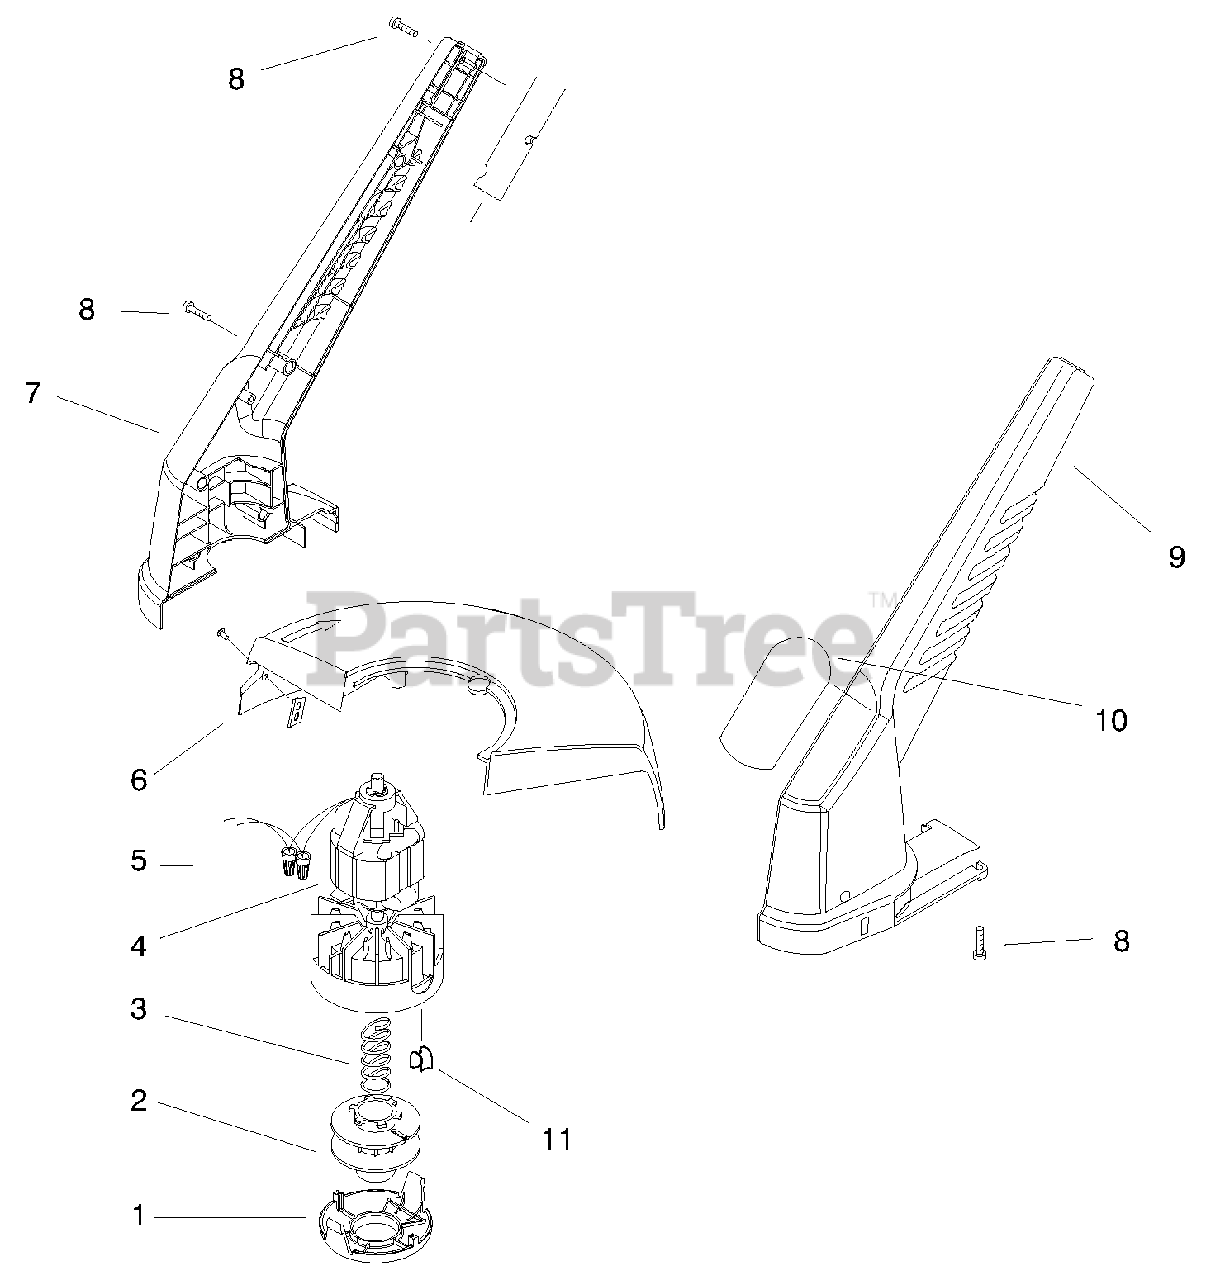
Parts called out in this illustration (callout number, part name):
2	SPOOL - LARGE
3	SPRING - COMPRESSION
4	Motor Assembly (Includes Ref. #11)
5	CONNECTOR-WIRE NUT
6	SHIELD ASM - SERVICE
7	HOUSING-RH
8	SCREW-PPH
9	HOUSING-LH
10	DECAL-14" TRIMMER
